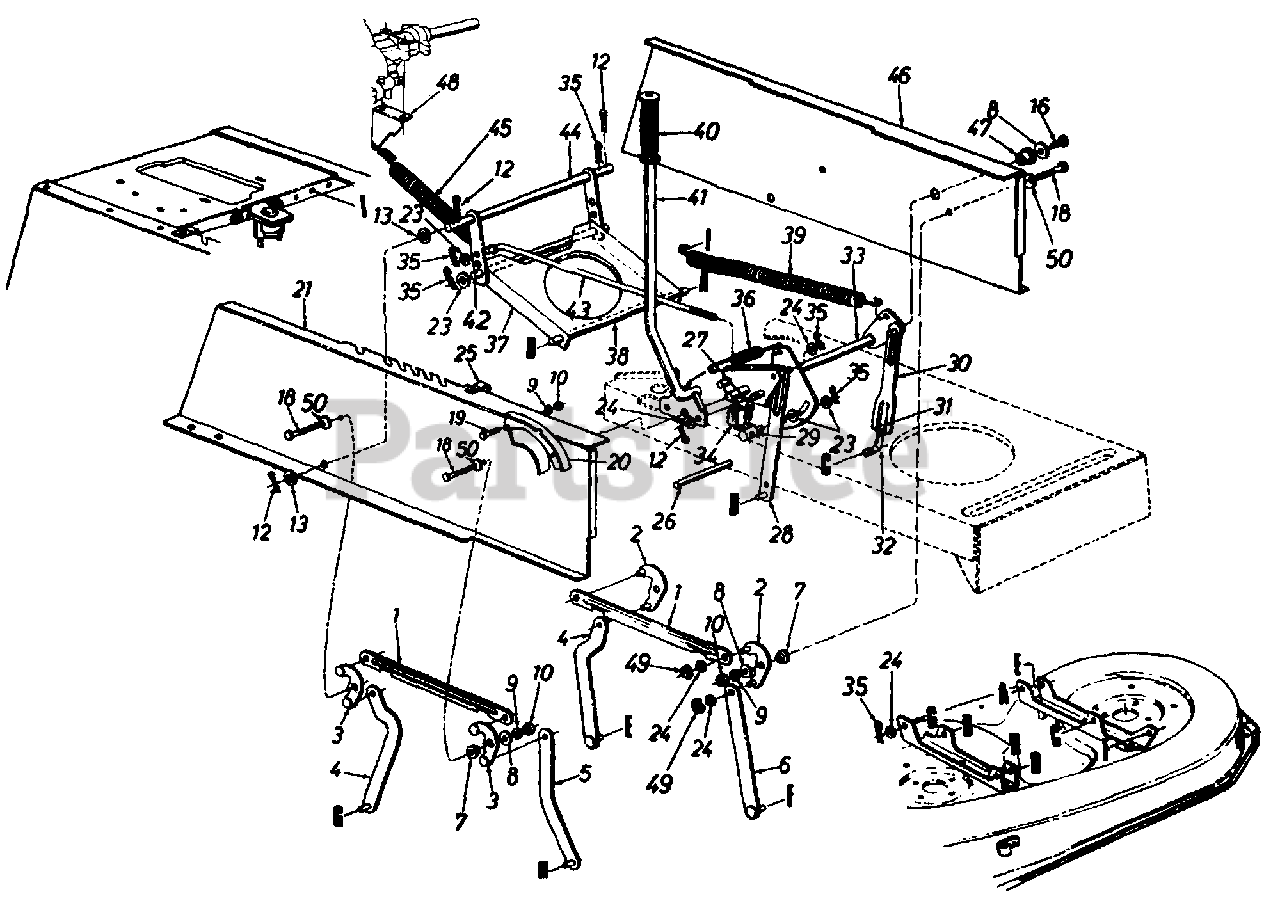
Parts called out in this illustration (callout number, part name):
3	Pivot Link Ass'y.- R.H.
7	Shld. Spacer .318" I.D.
8	Fl-Wash. .344" I.D. x .62" O.D.
9	L-Wash. 5/16" I.D.
10	Hex Nut 5/16-18 Thd. (Gr. 5)
12	Cotter Pin 1/8" Dia.
13	Fl-Wash. .635" I.D. x 1.0" O.D.
16	Hex Wash. TT-Tap Scr. 5/16-18 x .75" Lg.
18	Hex Wash. Hd. Scr. 5/16-18 x .875" Lg.
19	Hex Bolt 5/16-18 x .75" Lg.
24	Fl-Wash. .531" I.D. x .93" O.D.
26	Running Board Rod
27	Hex Wash. Hd. Tap Scr.
31	Hex Nut 1/2-20 Thd. (Gr. 5)
32	Lift Link Adjuster
33	Lift Shaft Ass'y.
34	Safety Switch
35	Inter. Cotter Pin 3/8" Dia.
36	Extension Spring
39	Extension Spring
40	Grip
43	Disengagement Rod
49	"E"-Ring
50	Bell-Wash. .325" I.D.
